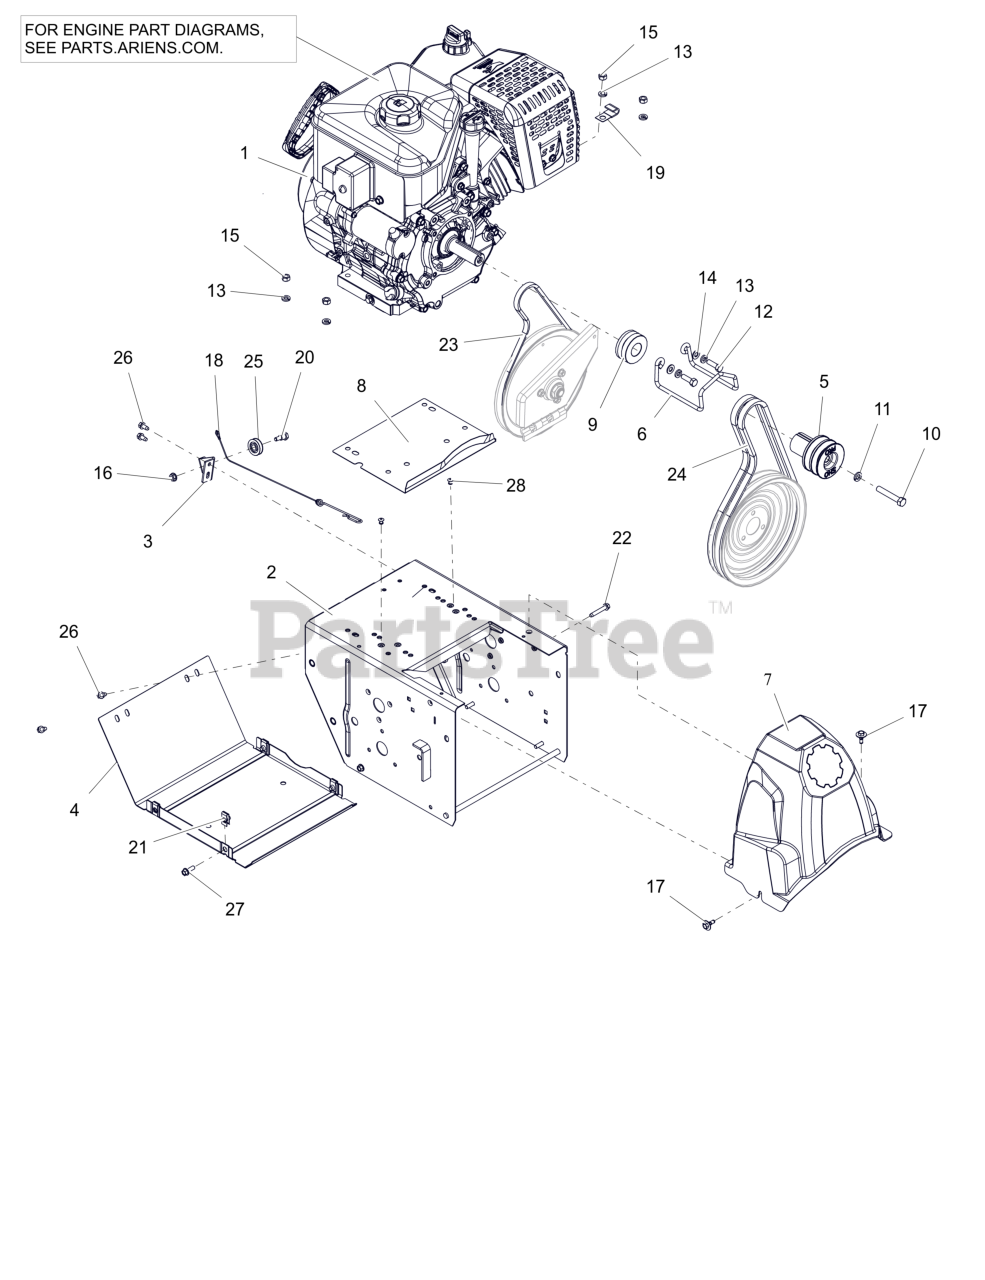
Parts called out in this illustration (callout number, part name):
1	ENGINE, AX369 GEN3 120V/60W
2	FRAME, MAIN - 14GA DELUXE (ORANGE)
3	BRACKET, CABLE PULLEY
4	COVER, BOTTOM
5	SHEAVE,ATTACHMENT-SHO 2 GRV
6	FINGER, BELT
7	COVER, BELT
8	BAFFLE, WATER - LARGE BLOCK
9	SHEAVE, TRACTION (KEYLESS)
10	BLT, HEX .38-24X2.25 G5 ZCC
11	WSHR,LK-REG .375X.094 ZCC
12	BLT, HEX 0.3125-24X1 G5 ZCC
13	WSHR, LK-HVY .312X.097 ZCC
14	WSHR,FLT .344X.688X.065 ZCC
15	NUT, HEX .312-18 ZCC
16	NUT-LK-TOP-FLG .250-20 GF ZCC
17	SCR-TAP .25-20X.5 CAPTIVE
18	CABLE, LOWER TRACTION,SS & PRO
19	J-CLAMP
20	BOLT, SHLDR -.375 X .375 X .25-20
21	NUT-RTNR .25-20X.56
22	SCR,TAP .25-20X1.50 HWH TR ZCC
23	V-BELT, 3L-WRAPPED
24	V-BELT, HA-RAW EDGE (SET)
25	PULLEY, CABLE
26	SCR-TAP .25-20X.50 HWH ZCC
27	BLT, HWH .25-20X.75 G5 ZCC
28	RVT, POP .1875 ZCC
